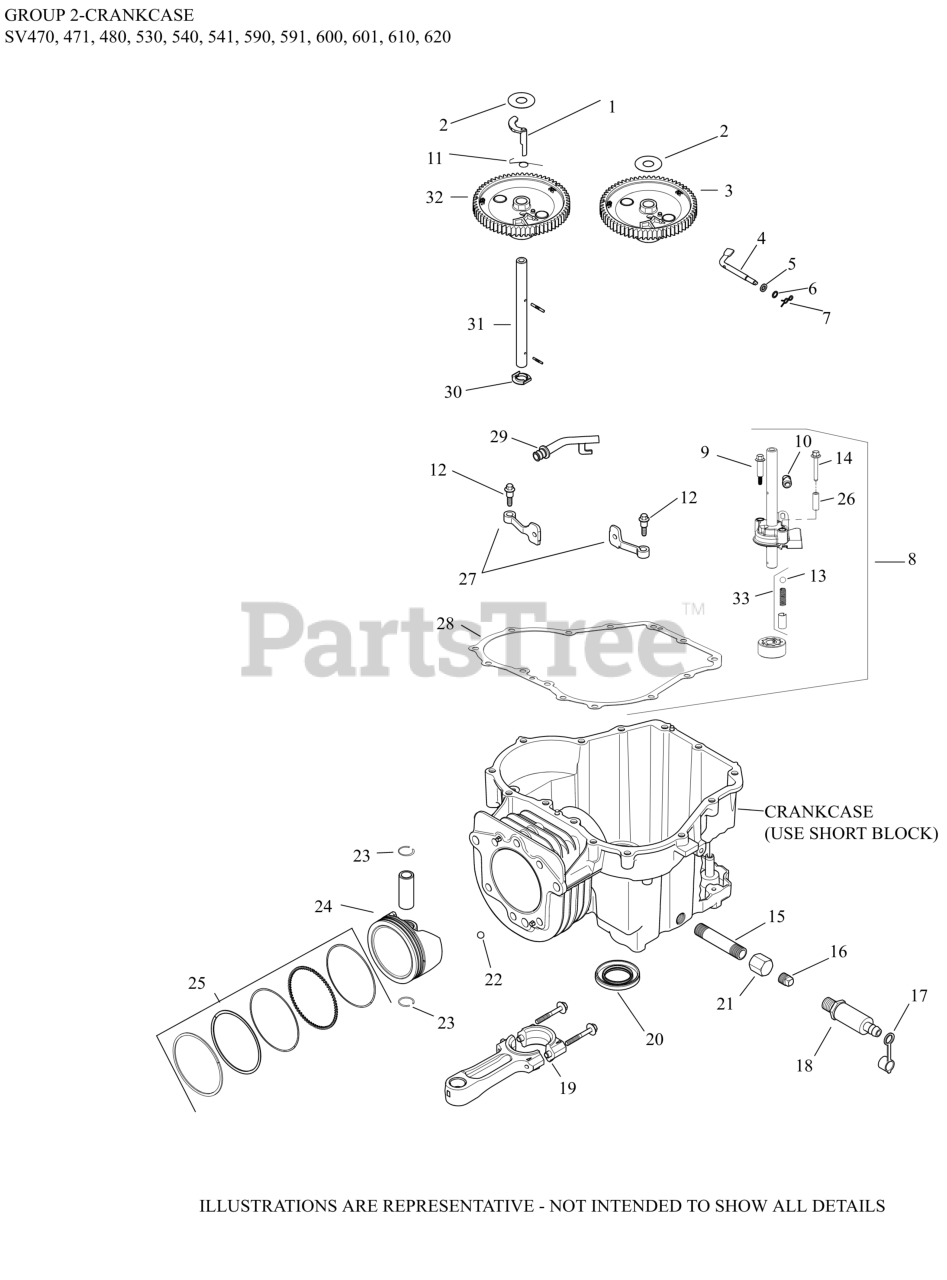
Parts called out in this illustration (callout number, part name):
1	KIT, ACR WEIGHT AND FOLLOWER
2	WASHER, THRUST -ACR
3	CAM GEAR ASSY (INTAKE) - USE 20 010 22-S
4	SHAFT, GOVERNOR CROSS
5	WASHER, FLAT 6 MM
6	WASHER, FLAT 1/4"
7	CLIP, HITCH PIN
8	KIT, OIL PUMP ASSEMBLY
9	SCREW, SHD THD FRM
11	SPRING, ACR
12	SCREW, SHD THD FRM M6X1X26
13	STEEL BALL
16	PLUG, SQ HD PIPE 3/8"
19	ROD, CONNECTING ASSEMBLY
20	SEAL, OIL
23	RETAINER, PISTON PIN
24	KIT, PISTON,RINGS & PIN ASSY 94mm BORE
25	RING SET (94MM)
27	KIT, CAM LEVER
29	TUBE, DRAINBACK
30	WASHER, THRUST
31	KIT,CAM CENTER SHAFT (EXHAUST)
32	CAM GEAR ASSY (EXHAUST) - (#2001023S)
33	KIT, OIL RELIEF-(#DSC)
